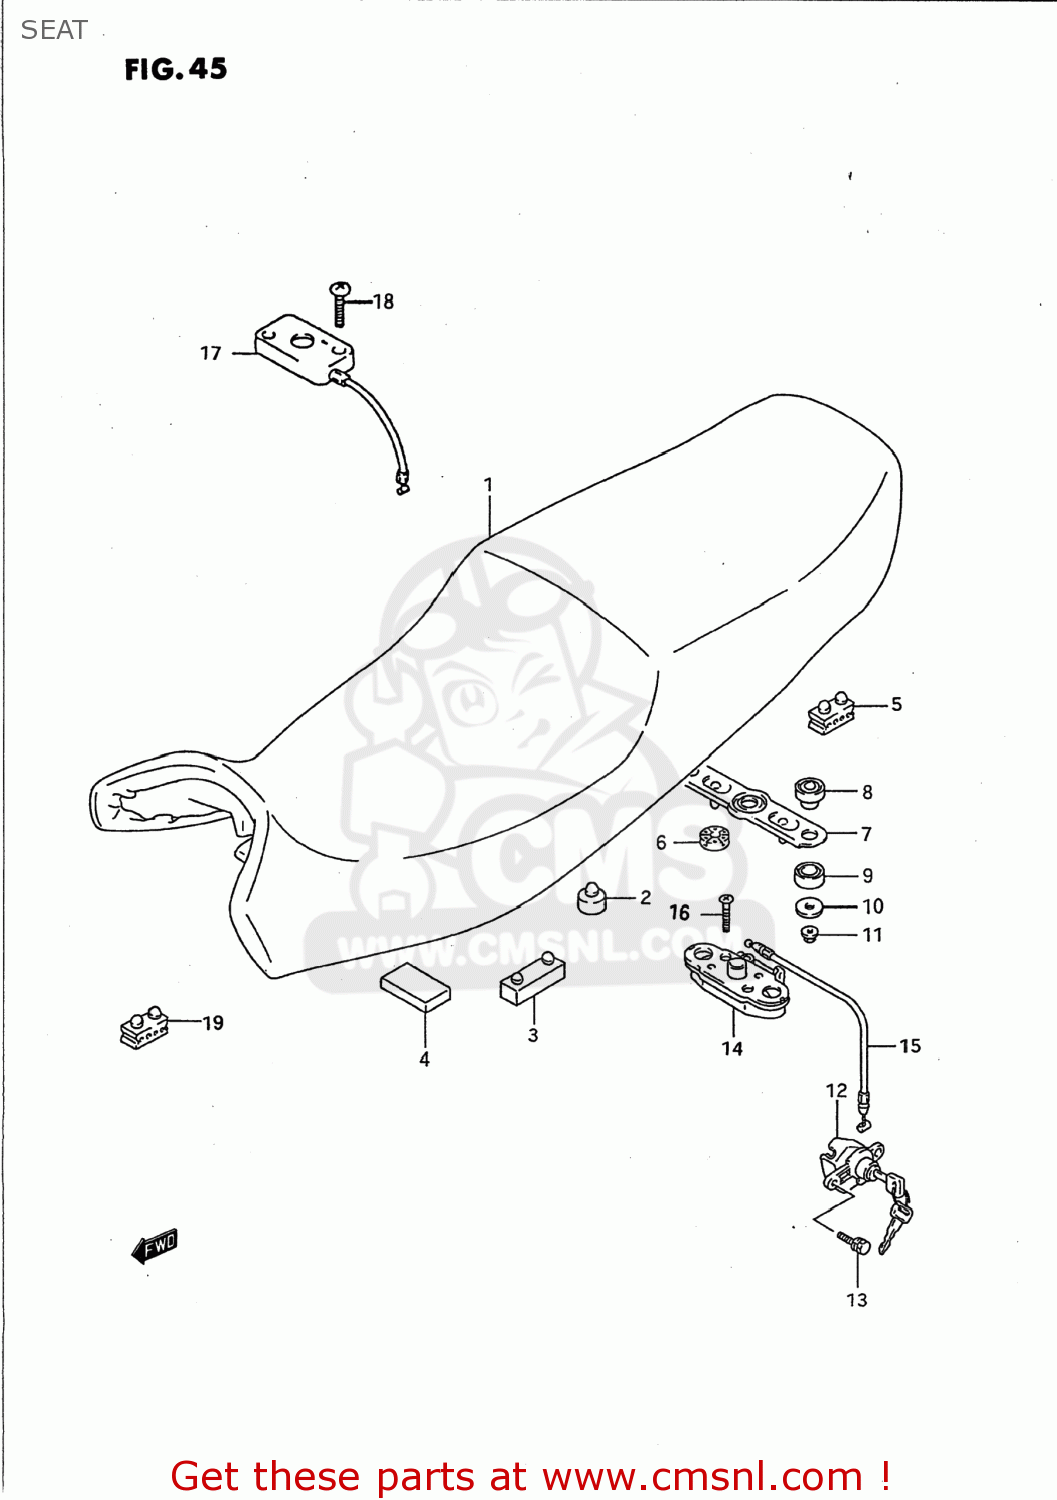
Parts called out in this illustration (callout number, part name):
1	SEAT ASSEMBLY
2	CUSHION
3	CUSHION,SEAT
4	CUSHION(30X60X10)
5	CUSHION,SEAT(40X20X15)
6	CUSHION,SEAT LOCK(10X22X6)
7	STRIKER,SEAT LOCK
8	CUSHION
9	CUSHION
10	WASHER
11	NUT
12	LOCK SET,SEAT
13	BOLT
14	BRACKET,SEAT SUPPORT,RIGHT
15	CABLE,SEAT LOCK
16	SCREW
17	BRACKET,SEAT SUPPORT FR
18	SCREW
19	CUSHION,SEAT(40X20X15)
